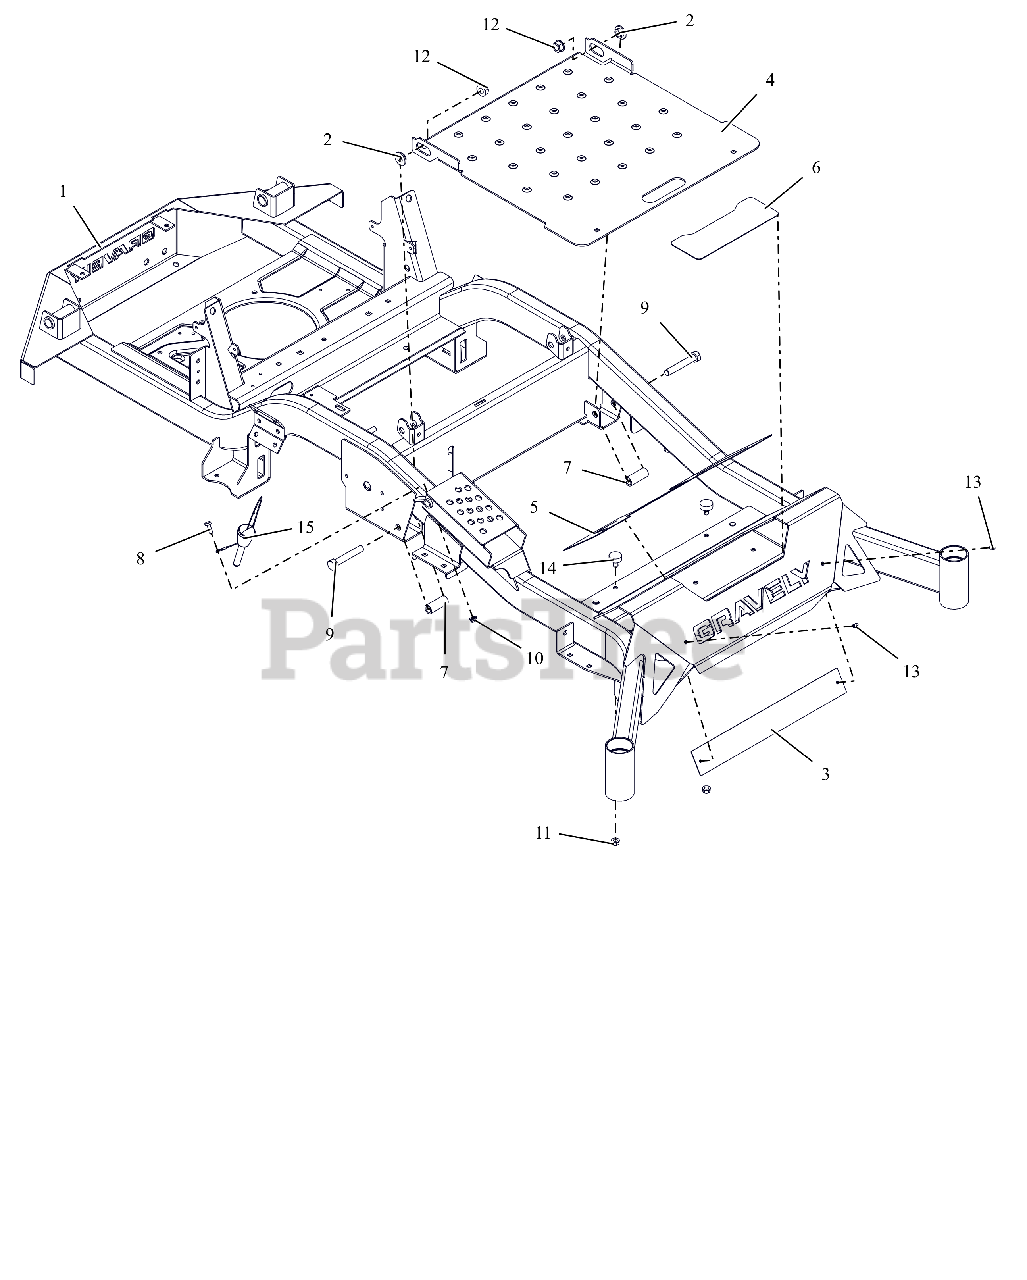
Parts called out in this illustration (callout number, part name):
1	HD 60"FRAME W/SAFETY DECALS
2	BSHG-FLG .515X.750X.310X1.120
3	PLATE, BACK FOOT-REST XL
4	KIT,ACCESS PANEL W/DECALS-RED
5	GRIP, FRONT
6	GRIP, STEP
7	SPACER, .515X.75X1.83
8	BLT, HEX .25-20X.75 G5 ZCC
9	BLT, HEX .50-13X3.00 G5 ZCC
10	NUT,NYL-FLG .25-20 GF ZCC
11	NUT,SPNLK-FLG .31-18 G5 ZCC
12	NUT-LK-TOP-FLG .500-13 GF ZCC
13	RIVET, .1875 AL/AL .126-.250
14	BUMPER, RUBBER
15	PIN, MAGNETIC .50X2.50
